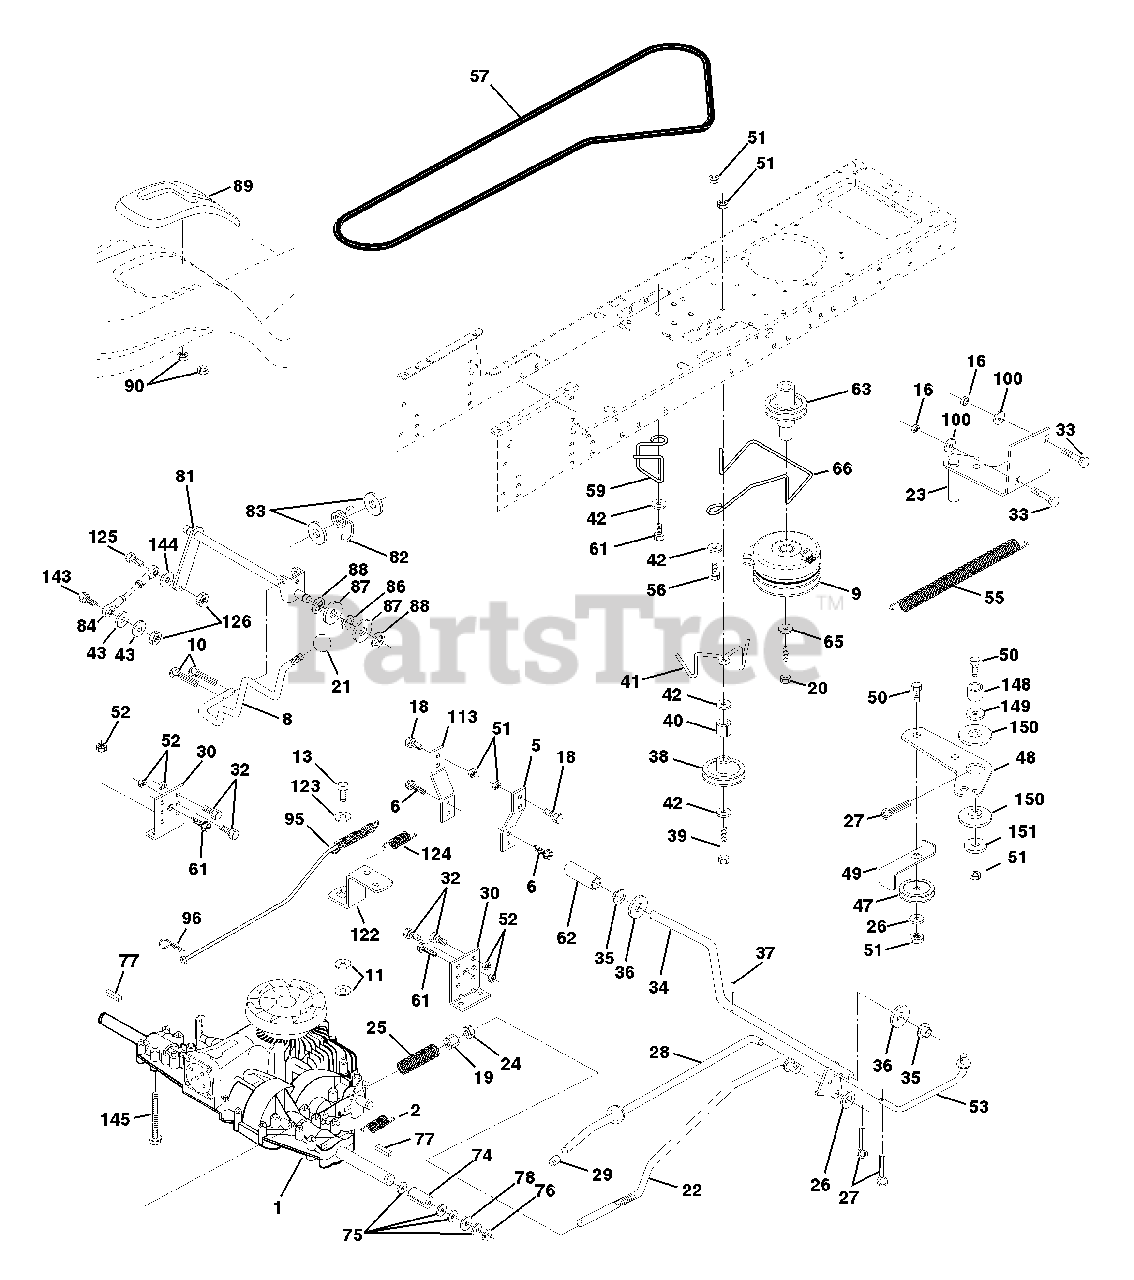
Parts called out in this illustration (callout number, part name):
1	Transaxle Peerless
2	Spring, Return Brake
5	Strap Torque
6	Screw Thdrol 5/16-18 x 3/4
8	Rod Shift Hydro LT
9	Clutch Elect
10	Pin Cotter 1/8 x 1 CAD
11	Washer Plate Shf .388 Sq Hole
13	Bolt 1/4-28 Unf Gr. 8 W/Patch
15	Bolt Hex Flghd 5/16-18 Gr. 5
16	Nut Lock Hx w/Ins 5/16-18 UNC
18	Bolt Fin Hex 3/8-16 Unc x 1 Gr. 5
19	Nut Lock Hex W/Wsh 3/8-16 Unc
20	Bolt Hex 7/16-20 x 4-1/4 5 Ga. 1.38
22	Rod, Brake
23	Bracket Asm Mtg. Cl
24	Nut, Hex Jam 3/8-16 Unc
25	Spring, Brake Rod
26	Washer
27	Pin Cotter 1/8 x 3/4 CAD.
28	Rod, Parking Brake
29	Cap, Parking Brake
30	Bracket, Transaxle
32	Bolt Hex Hd 5/16-18 Unc x 3/4
33	Bolt Rd Hd Sqnk 5/16-18 Unc x 3/4
34	Shaft, Foot Pedal
35	Bearing, Nylon
37	Pin, Roll
38	Pulley, Idler, Flat
40	Spacer, Split
41	Keeper, Belt, Idler
42	Washer 13/32 x 13/16 x 12 Gauge
43	Washer 11/32 x 5/8 x 12 Ga.
47	Pulley, Idler, V-Groove
48	Bellcrank Assembly
49	Retainer, Belt
50	Bolt
51	Nut Crownlock 3/8-16 UNC
52	Nut, Crownlock 5/16-18 Unc
53	Link, Clutch
55	Spring, Return, Clutch
56	Bolt Hex 3/8-16 x 1-1/4
57	V-Belt, Ground Drive
59	Keeper, Center Span
61	Screw Thdrol. 3/8-16 x 3/4 Ty. TT
62	Cover, Pedal
63	Pulley, Engine
65	Washer
66	Keeper Belt Engine
74	Spacer, Axle PVST
75	Washer 25/32 x 1-1/4 x 16 Gauge
77	Key, Square
78	Washer 25/32 x 1-5/8 x 16 Gauge
81	Shaft Asm. Cross Hydro
82	Spring Torsion T/A
83	Washer 17/32 x 3/4 x 16 Ga.
84	Rod, Tie PVST 18"
86	Bushing Rod Strig. 629/632 ID
87	Washer 21/32 x 1-1/4 x 16 Ga.
88	Ring Klip #5304-62
89	Console, Shift
90	Nut Self-Thd Wsh-Hd 1/4 Zinc
95	Rod Asm Bypass PVST
96	Retainer Spring 1" Zinc/Cad
100	Washer 11/32 x 3/4 x 16 Ga.
113	Strap Torque LH LT
118	Spacer Bellcrank
121	Nyliner Clutching STL
122	Plate Bypass PVST
123	Washer 9/32 x 5/8 x 16 Ga.
124	Spring Return PVST
125	Bolt Fin Hex 5/16-18 Unc x 1
126	Nut Lock 5/16-18 Unc
143	Bolt Fin Hex 5/16-18 UNC x 1-1/4
